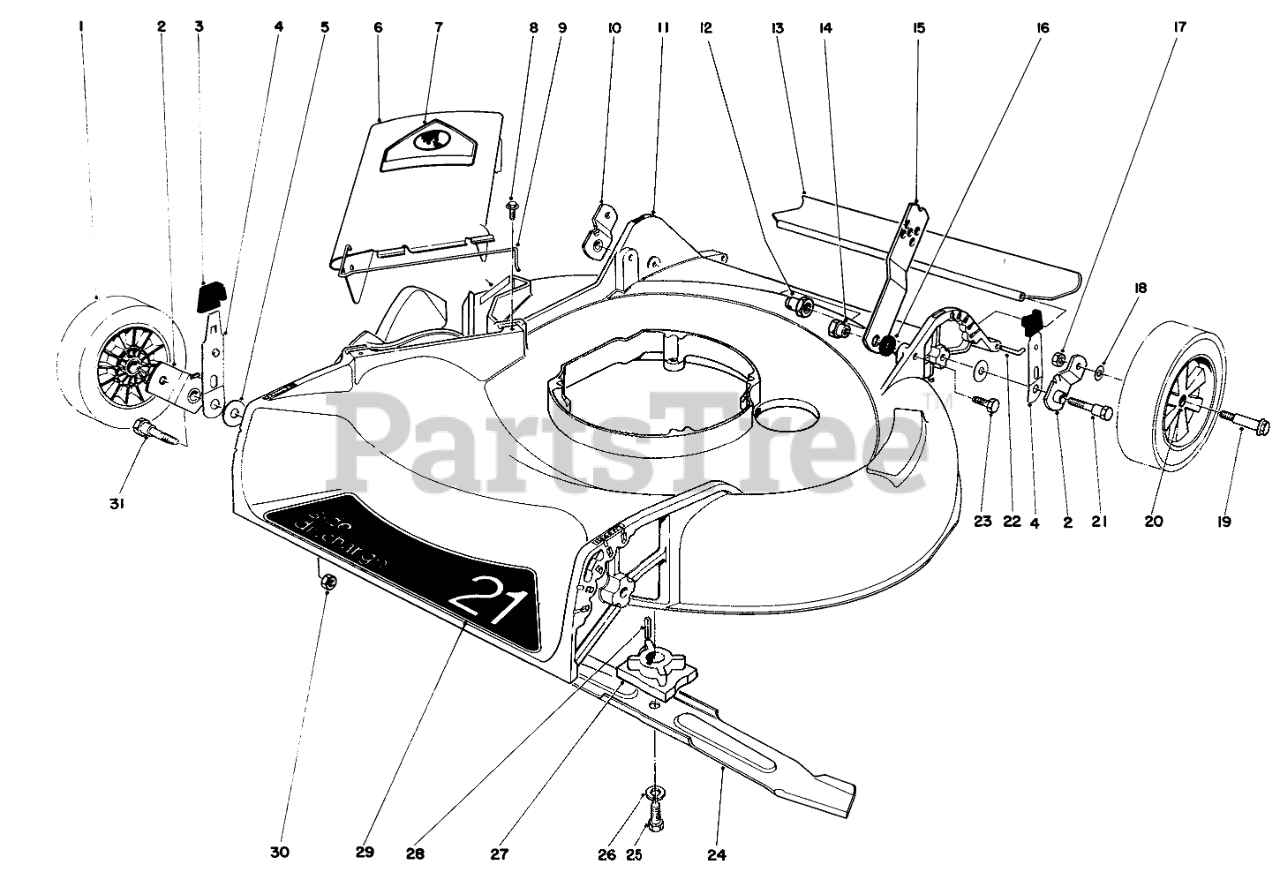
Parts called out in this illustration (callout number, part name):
1	Wheel & Tire Assembly (Incl. Ref. #19)
2	Pivot Arm
3	KNOB-ARM
4	SPRING ARM ASM
5	WASHER-PIVOT
6	Deflector Assembly (Incl. Ref. #7&9)
7	DECAL-DANGER
8	SCREW-HWH
9	SPRING HINGE
10	Pivot Arm
11	HOUSING/DECAL
12	HANDLE PIVOT NUT
13	REAR SAFETY SHIELD 21
14	HANDLE PIVOT NUT
15	Handle Latch
16	SPACER
17	Nut
18	WASHER
19	BOLT-WHEEL
20	BUSHING
21	5/16-18 PIVOT SCREW
22	SHIELD ROD
23	SCREW-HH
24	Blade
25	SCREW-HH
26	WASHER-LOCK
27	Retainer Blade
28	KEY-SQUARE
29	Decal-Side Discharge
30	NUT-LOCK, NI
31	PIVOT SCREW
